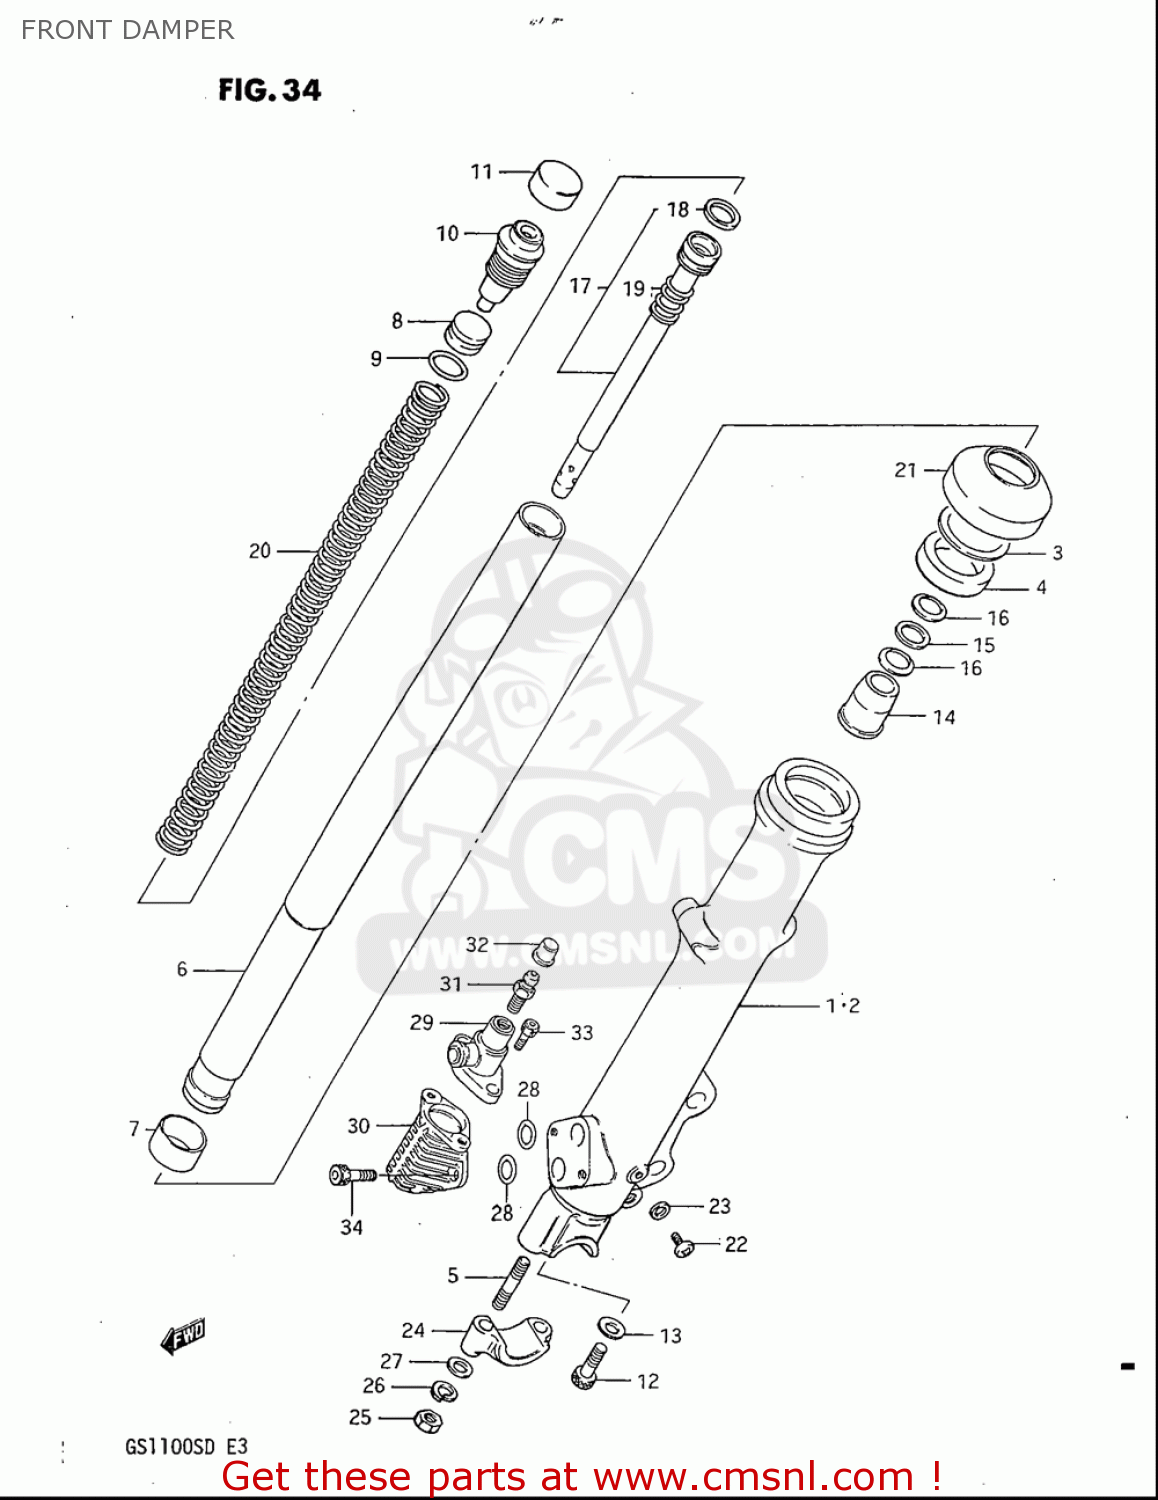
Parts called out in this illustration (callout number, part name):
1	TUBE,OUTER,R
2	TUBE,OUTER,LEFT
3	RING,STOPPER
4	SEAL,OIL
5	STUD 8X30
6	INNER TUBE
7	PISTON
8	PISTON,FREE
9	O RING(D:3.5,ID:21.8)
10	CAP
11	CAP,RUBBER
12	BOLT,FORK CYLINDER(10X25)
13	GASKET (NAS)
14	PIECE,OIL LOCK
15	WASHER
16	SPRING,LEAF
18	RING,PISTON
19	SPRING,REBOUND
21	SEAL,DUST
22	SCREW
23	GASKET,DRAIN,PLUG (NAS)
24	HOLDER,AXLE
25	NUT
26	WASHER,LOCK
27	WASHER
28	O RING(D:2.4,ID:11.8)
31	BREATHER,AIR
32	CAP,BLEEDER PLUG
34	BOLT
